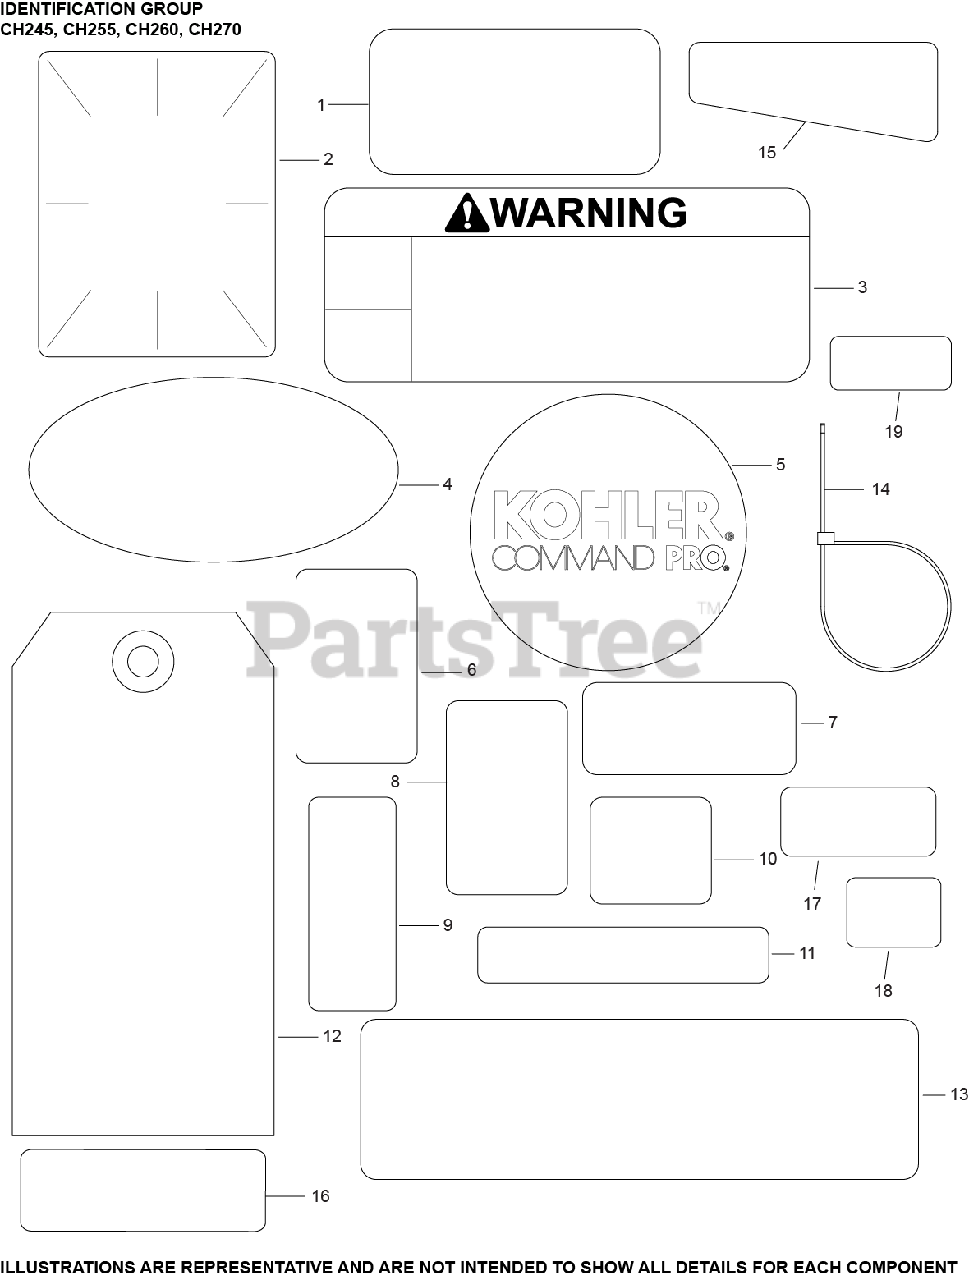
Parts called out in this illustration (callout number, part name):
1	LABEL, MAINTENANCE (CKY)
2	LABEL, CLEAR LAMINATION
5	LABEL, RECOIL 62MM
10	LABEL, LPAC CHOKE
